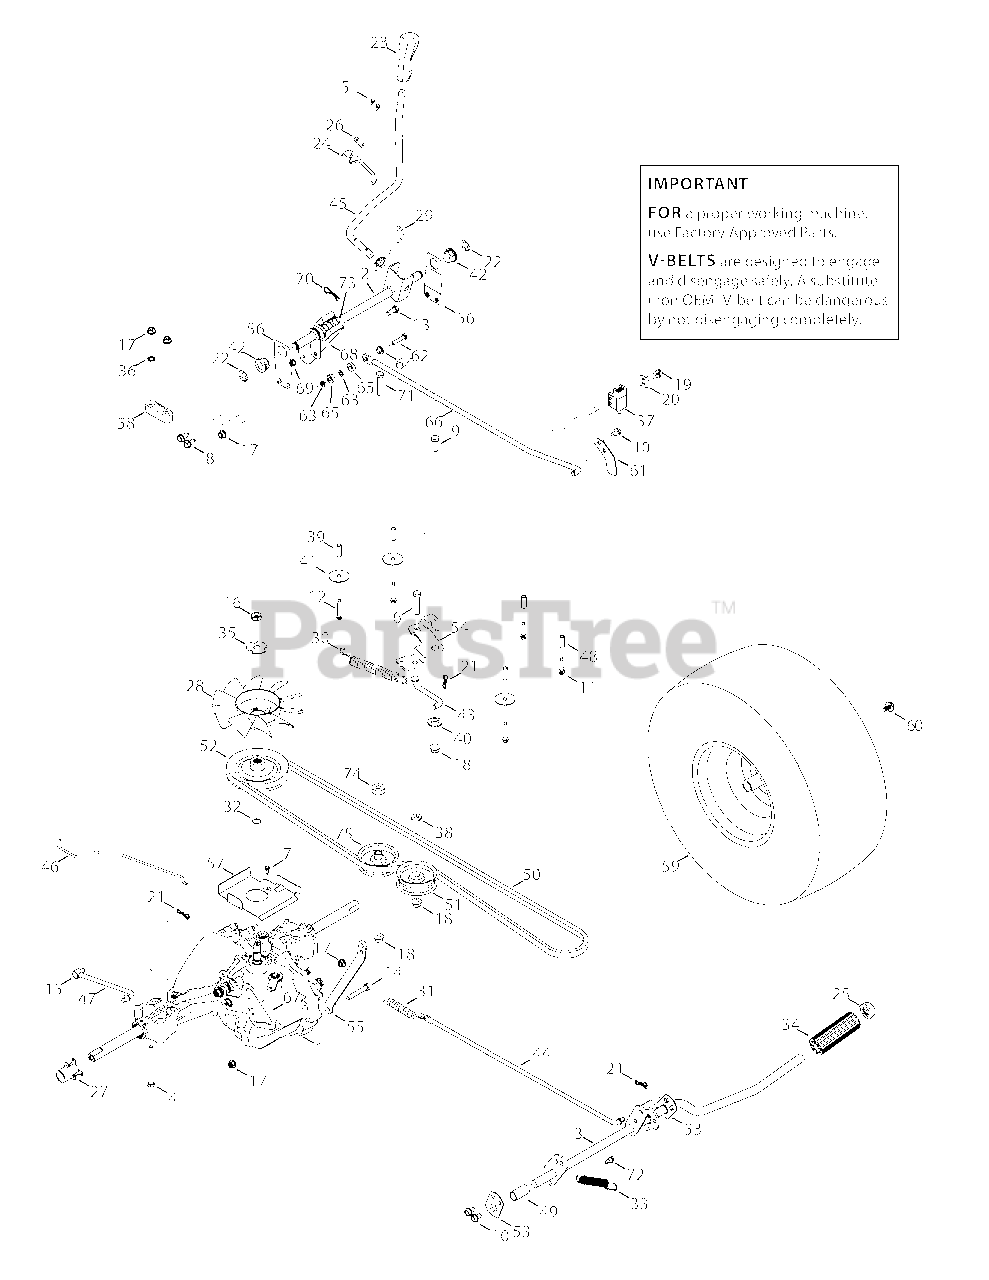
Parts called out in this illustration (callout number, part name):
1	Hydro Transmission
2	Hydro Handle Control Assembly
3	Hydro Pedal Assembly
4	Hex Screw, 5/16-18 x 3.5
5	Screw, #8-18:0.500
6	Hex Screw, 3/8-16:1.75
7	Screw, #10-16:0.500
8	Screw, 5/16-18:.750
9	Hex Screw, 3/8-16:1.00
10	Screw, 5/16-18:0.625
11	Screw, 1/4-20:1.250
12	Screw, 1/4-20 x 1.75
13	Hex Screw, 5/16-18:.75
14	Screw, 5/16-18 x 2.00
15	Ferrule, 5/16-24 X .312 DIA.
16	Jamlock Nut, 1/2-20
17	Flangelock Nut, 5/16-18
18	Flangelock Nut, 3/8-16
20	Plate Switch
21	Cotter Pin, Bow Tie
22	E Rign, .625 DIA
23	Handle Grip
24	Hydro Spring Switch
25	Push Cap, 5/8
26	Insulator Plate Nut
27	Sleeve, .765 ID X 2.11 LG
28	Hydro Fan
29	Torsion Spring
30	Extension Spring, .75 DIA. X 6.02
31	Extension Spring, .59 OD X 4.00 LG
32	Wire Ring
33	Extension Spring, .63 DIA X 4.95 LG
34	Foot Pad, 4.0
35	Lock Washer, TRANS HYDRO
36	Lock Washer, 5/16 EXT TOOTH
37	Switch Interlock
38	Flat Washer, .407X.812X.135:HT
39	Spacer, .260 x .372 x 1.420
40	Shldr Spacer, 1.375 ID X .380 x 1.54
41	Flat Washer, .350 x 1.59 x .062
42	Hex Flange Bearing
43	Declutching Rod
44	Brake Rod
45	Hydro Control Handle
46	Hydro Bypass Rod
47	Hydro Control Rod
48	Spacer, .260 x .375 x 1.030 LG
49	Spacer, .640 ID X .76 OD X 1.60
50	V Belt, 4L SEC X 84.17
51	Flat Idler Pulley 2.75 OD
52	Input Pulley
53	Support Pedal Bracket
55	Torque Bracket
56	Handle Bracket
57	Belt Support Bracket
58	Spacer, T-Axle
59	Wheel, 20 x 8 x 8 - Grey
60	Screw, 5/16-24 x .750
61	Stop Pedal Plate
62	Hex Screw, 1/4-20 x 1.50
63	Lock Washer, 1/4
64	Shoulder Spacer, .375 x .625 x .20
65	Ball Bearing, .25 x .6875 x .25
66	Hydro Rod, RTN
67	Cam Bracket, RTN
68	Pivot Bracket, RTN
69	Nut, Flange Lock, 1/4-20, GrF
70	Click Pin, .092 x 1.64 LG
71	Hex Screw, 3/8-16 x 2.00
72	Shoulder Screw, 1/4-20 x 0.50
73	Hex Flange Bearing, .628 ID
74	Spacer, .406 ID x 1.00 OD x .38
75	V Pulley 3.06 OD
